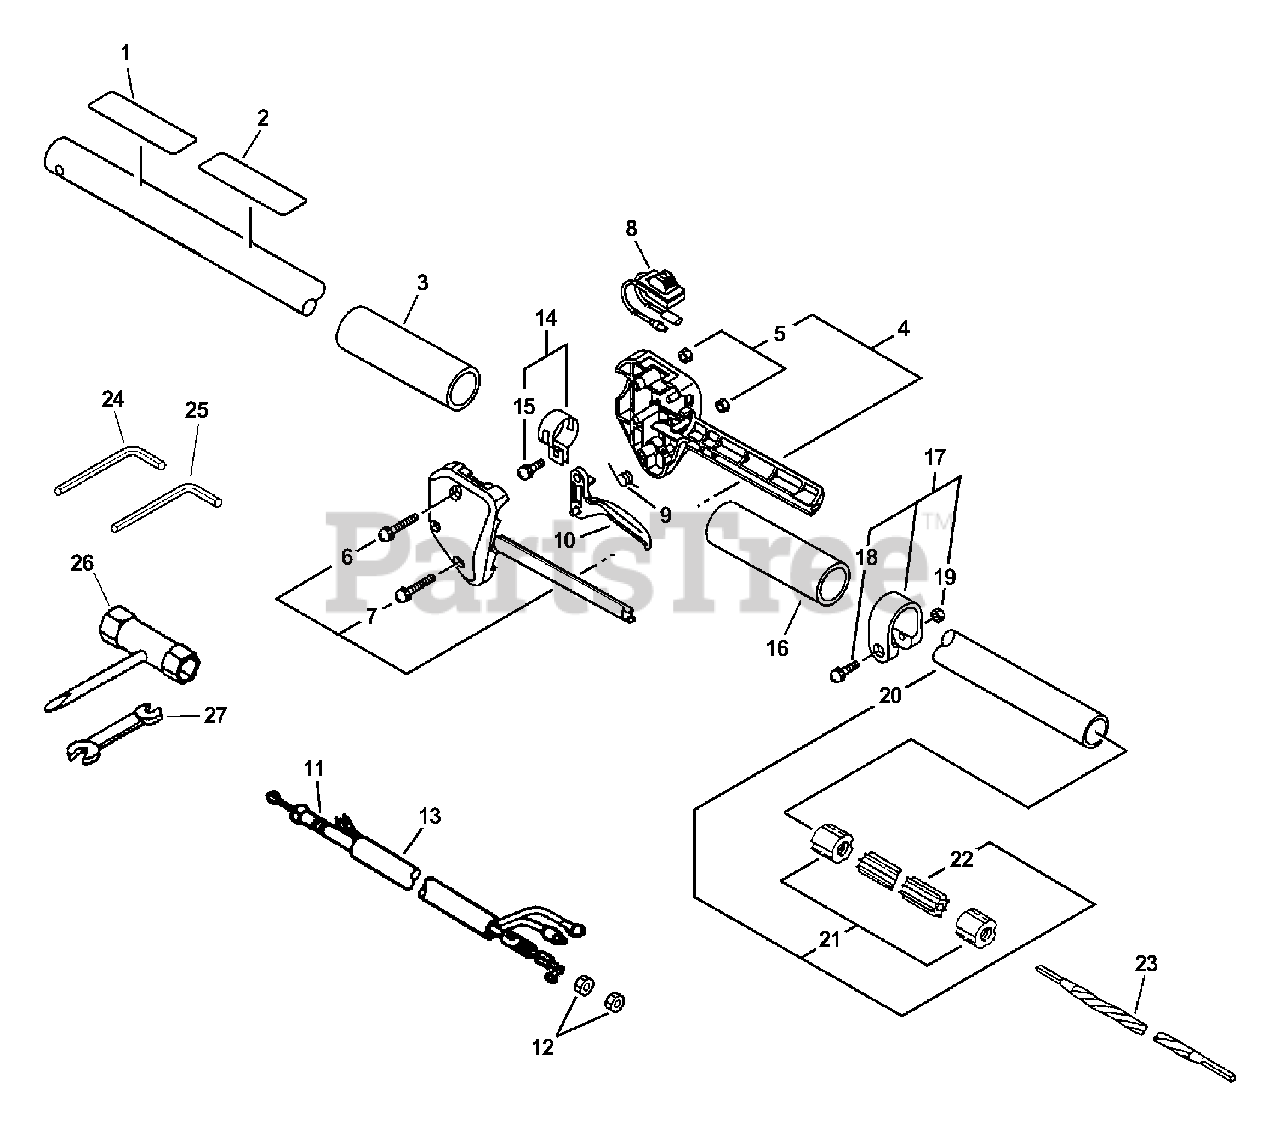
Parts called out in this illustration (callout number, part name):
1	LABEL, CAUTION
2	LABEL - CAUTION
3	GRIP, HANDLE
4	HANDLE KIT, CONTROL
5	NUT M5
6	SCREW 5×35
7	SCREW 5×25
8	SWITCH ASSY, ON-OFF
9	SPRING, TORSION
10	TRIGGER, THROTTLE
11	CABLE, THROTTLE
13	TUBE
14	CLAMP KIT
15	SCREW 5×12
16	GRIP, HANDLE
17	CLAMP KIT
18	SCREW 5×28
19	NUT M5
20	MAIN PIPE ASSY
22	LINER - FLEXIBLE
23	DRIVESHAFT - FLEXIBLE
24	WRENCH, ALLEN 4 MM
25	WRENCH, ALLEN 3 MM
26	T-WRENCH 17x-19 L200
27	SPANNER 8×10
